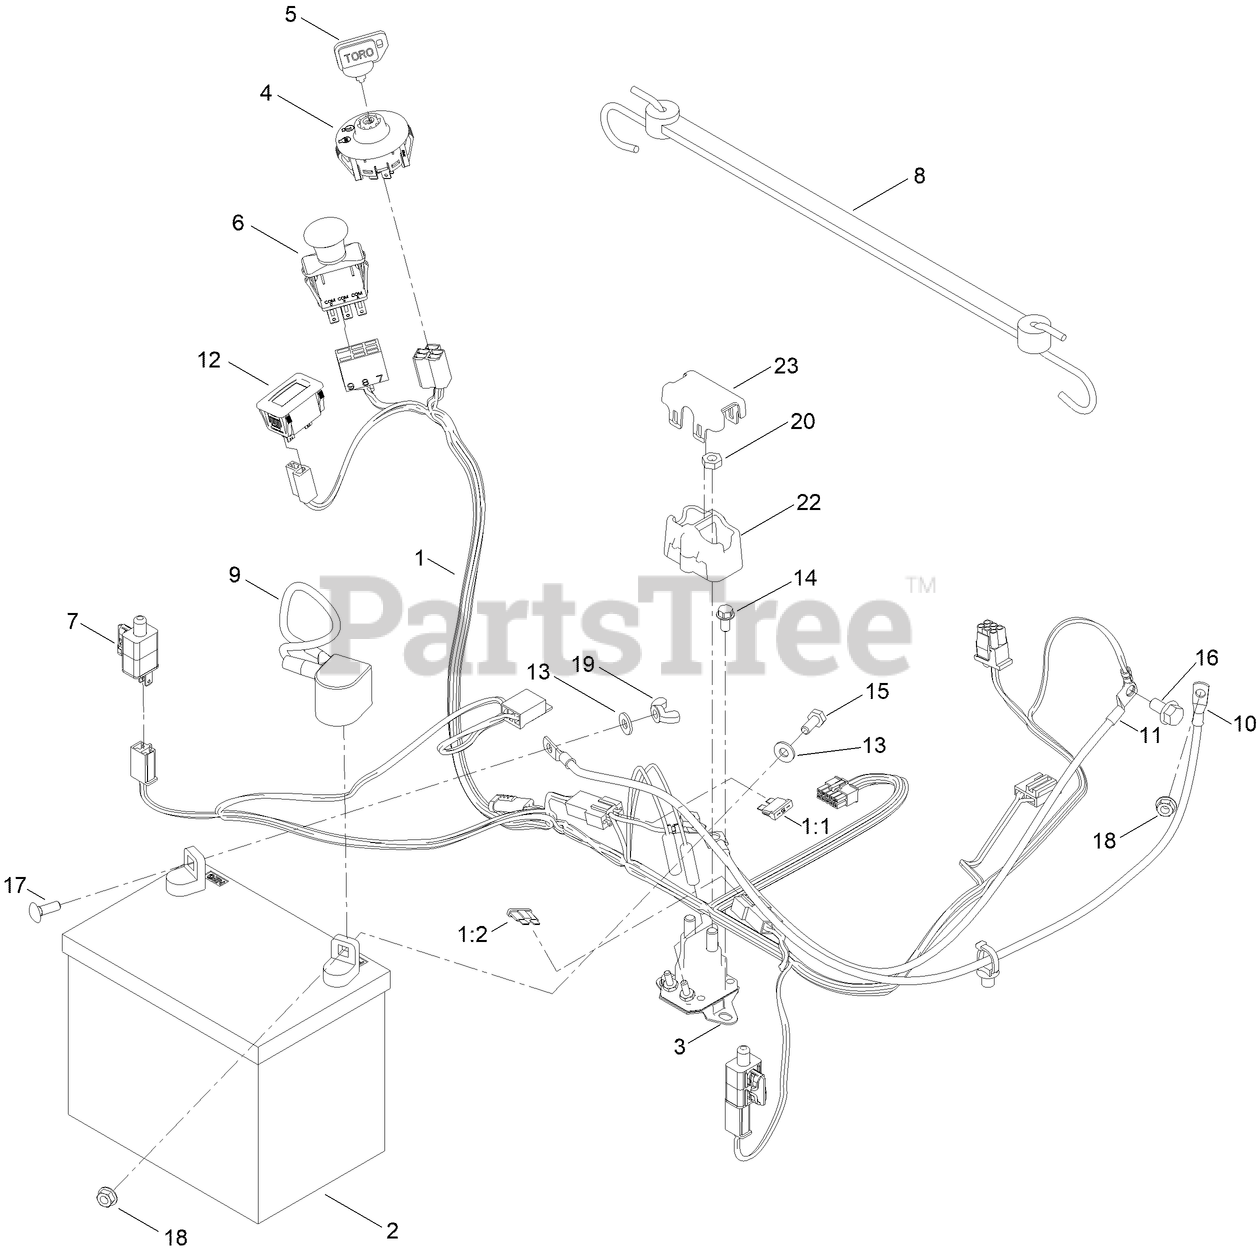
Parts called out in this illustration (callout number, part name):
1	HARNESS-WIRE
1:1	FUSE-BLADE, 15 AMP
1:2	FUSE-BLADE, 25 AMP
2	BATTERY
3	SOLENOID
4	SWITCH-IGNITION
5	KEY-IGNITION
6	SWITCH-PTO
7	SWITCH
8	STRAP-RUBBER
9	CABLE-BATTERY, POS
10	CABLE-BATTERY, RED (8 GAUGE)
11	CABLE-BATTERY, BLACK
12	HOURMETER
13	WASHER-FLAT
14	SCREW-HWH
15	SCREW-HH
16	SCREW-HHF
17	BOLT-CARR
18	NUT-HF
19	NUT-WING
20	NUT-JAM
22	COVER-SOLENOID
23	CAP-SOLENOID
